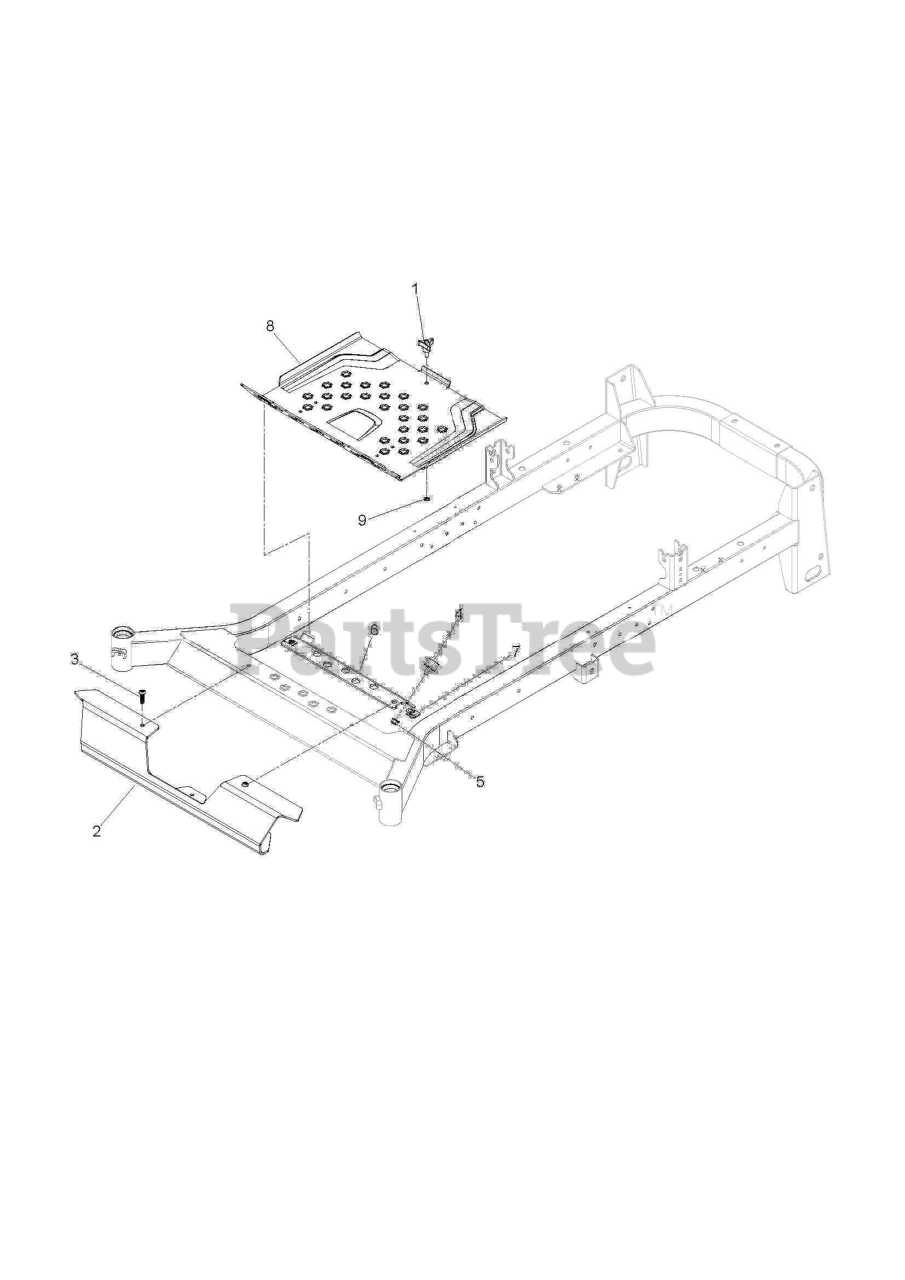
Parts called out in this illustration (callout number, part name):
1	GSPW Knobs
7	SCREW.BUTTON.HEAD.TORX.3/8-161
8	PLATE.PNT.FOOTREST.PZ.ORANGE
